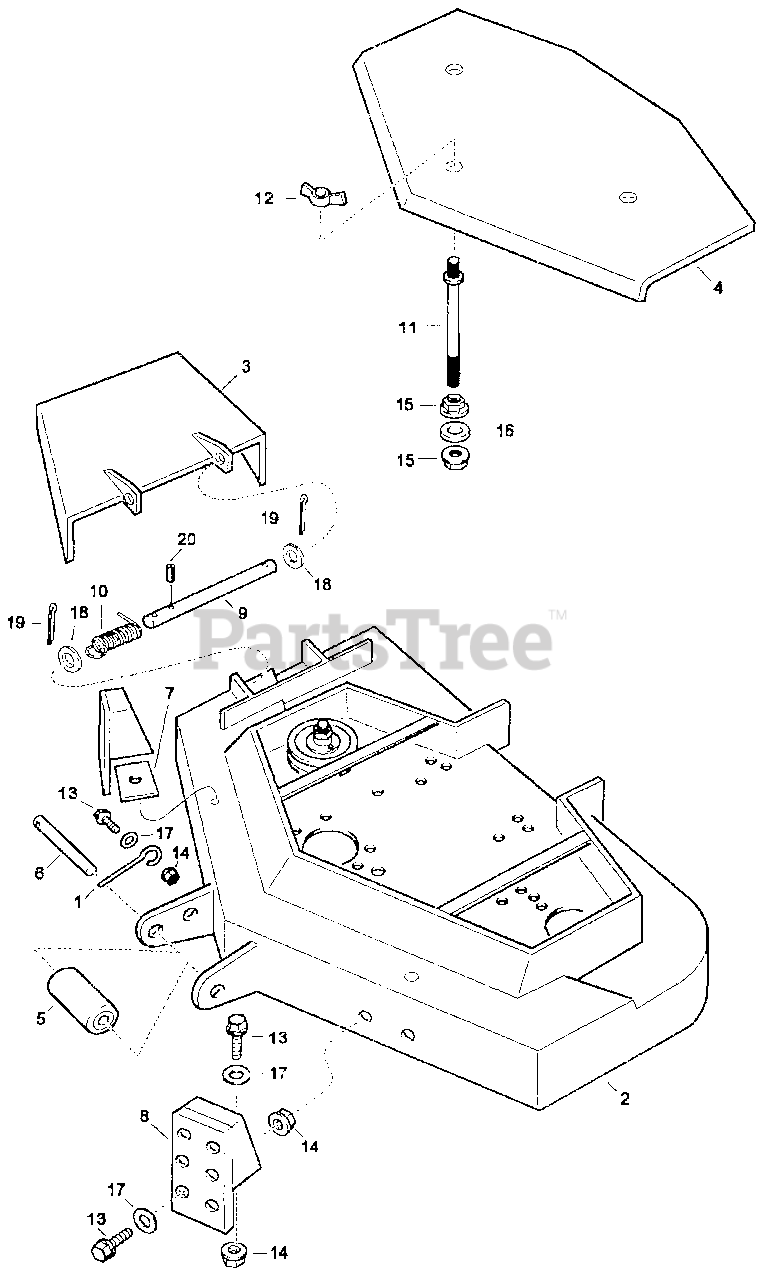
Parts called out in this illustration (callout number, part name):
2	HOUSING, CUTTER (60")
3	ADAPTER, DISCHARGE
4	COVER, BELT
5	ROLLER ASSY., ANTI-SCALP
6	SHAFT, ANTI-SCALP
7	PLATE, GAUGE ROLLER
8	BRACKET
9	SHAFT, DISCHARGE
10	SPRING, GUARD SET
11	STUD, HOOD MOUNT
12	WINGNUT (5/16"-18)
